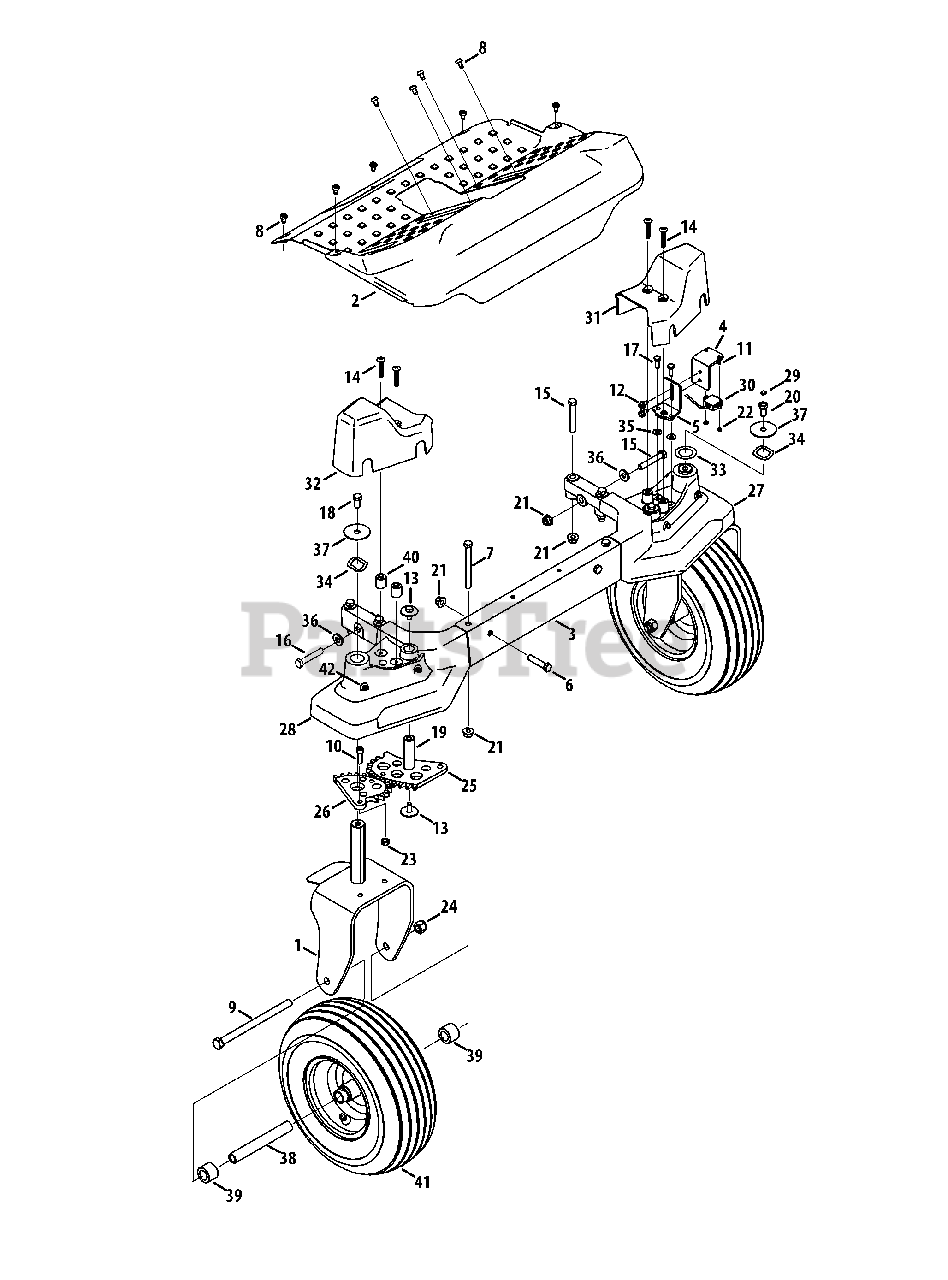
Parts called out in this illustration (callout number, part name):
1	Caster Wheel Bracket
2	Floor Board
4	Steering Sensor Mounting Bracket
5	Sensor Adjustment Mounting Brkt.
6	Hex Cap Screw, 3/8-16 x 1.75
7	Hex Cap Screw, 3/8-16 x 4.0
8	Self Tapping Screw, 1/4-20 x .50
9	Bolt, 1/2-20 x 7.25
10	Socket Head Screw, 5/16-18 x 1.00
11	Screw, #5-40 x .625
12	Hex Washer Screw, 1/4-20 x .500
13	Hex Cap Screw, 5/16-18 x .75
14	Screw, 1/4-20 x 1.50
15	Hex Cap Screw, 3/8-16 x 2.50
16	Hex Cap Screw, 3/8-16, 2.25
17	Hex Cap Screw, 1/4-20 x 0.75
18	Hex Screw, 3/8-16 x .75
19	Pivot Gear Steering Shaft
21	Flange Lock Nut, 3/8-16
22	Hex Lock Nut, #5-40
23	Hex Lock Nut, 5/16-18
24	Hex Lock Nut, 1/2-20
25	12-Tooth Variable gear
26	13-Tooth Variable gear
27	Pivot Axle, LH
28	Pivot Axle, RH
29	Magnet-Rotary Sens
30	Sensor-Rotary
31	Axle Cover, LH
32	Axle Cover, RH
33	Flat Washer, 1.006 x 1.56 x .020
34	Wave Washer, 1.5 x 1.0 x .029
35	Flat Washer, .25 x .63 x .052
36	Flat Washer, .406 x .875 x .105
37	Flat Washer, .406 x 1.92 x .060
38	Spacer, .51 ID x .75 OD x 5.825
39	Hub, .76 x 1.23 x .92 LG
40	Shoulder Spacer, .28 x .75 x .837
41	Wheel Assembly, 13 x 5-6
42	Grease Fitting
